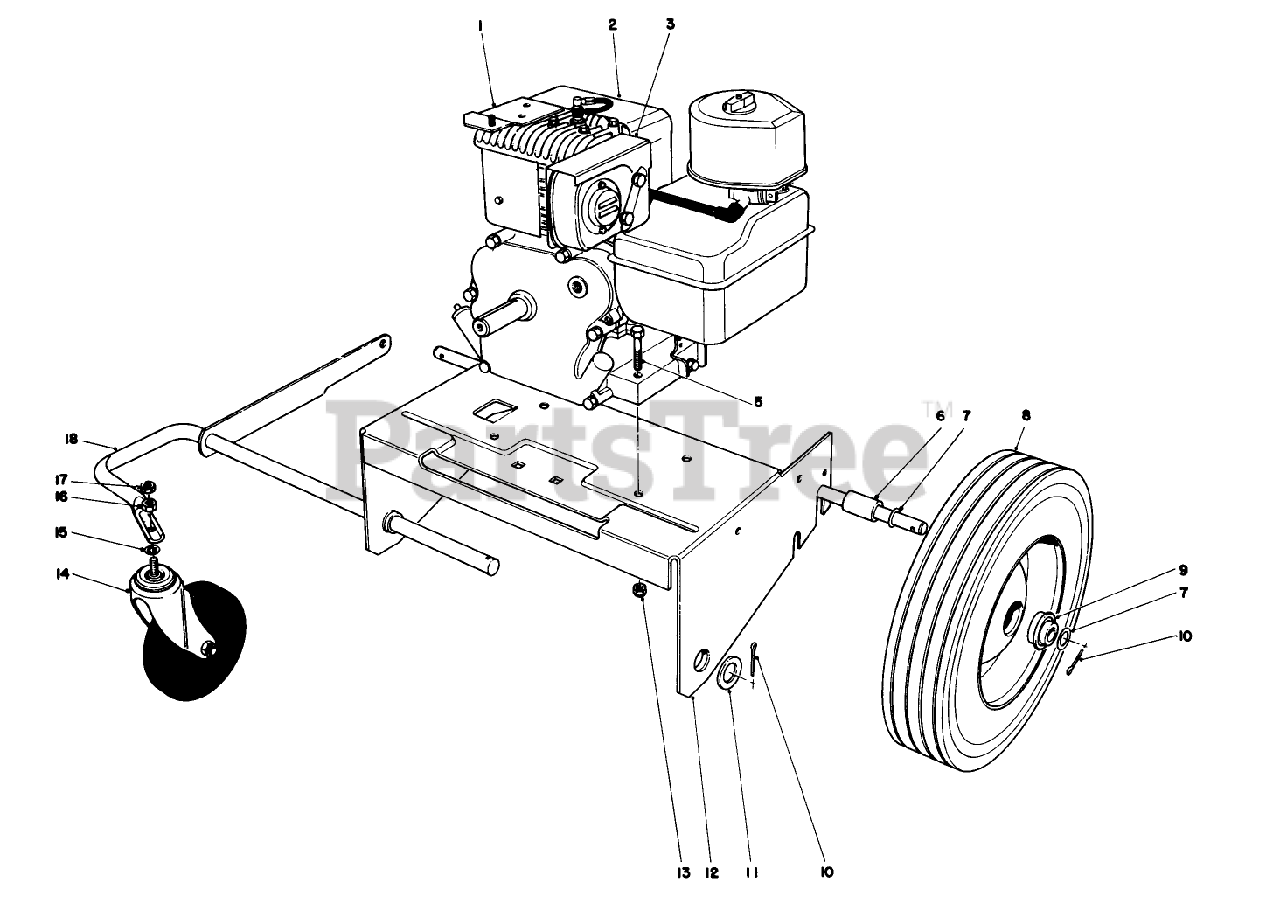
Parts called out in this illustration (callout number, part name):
1	MTG BRKT WA *B
2	Engine
3	HEAT SHIELD
5	SCREW-HH
6	SPACER-AXLE
7	WASHER
8	WHEEL
9	BEARING
10	PIN-COTTER
11	WASHER-FLAT
13	NUT-LOCK, CONE
14	CASTER
15	WASHER-LOCK/INT
16	NUT-HH
